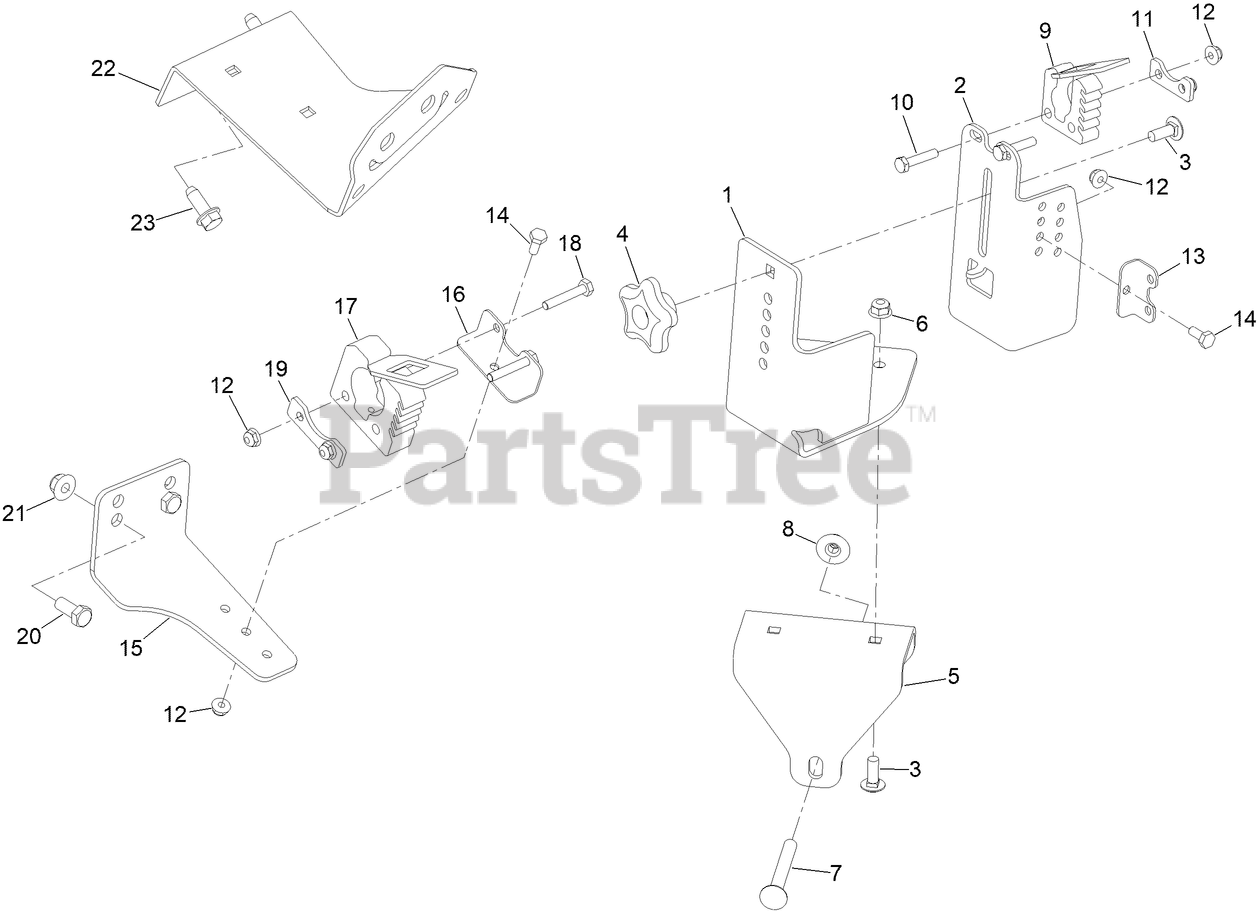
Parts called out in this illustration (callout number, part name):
1	PLATE-MOUNT, TRIMMER
2	PLATE-TRIMMER, ADJ.
3	BOLT-CARR
4	KNOB-HANDLE
5	CHANNEL-BRACKET, WEIGHT
6	NUT-HF, NI
7	SCREW-CARR
8	NUT-FLANGE, NI
9	CLAMP-QUICK FIST, MINI
10	SCREW-HH
11	PLATE-BACKER, SMALL
12	NUT-HF
13	BRACKET-QUICK FIST, SMALL
14	SCREW-HH
15	BRACKET-TRIMMER, REAR
16	BRACKET-QUICKFIST, LARGE
17	CLAMP-QUICK FIST, ORIGINAL
18	SCREW-HH
19	PLATE-BACKER, LARGE
20	SCREW-HH
21	NUT-HF, NI
22	BRACKET-SUPPORT, POD (RH)
23	SCREW-FORMING, THREAD
